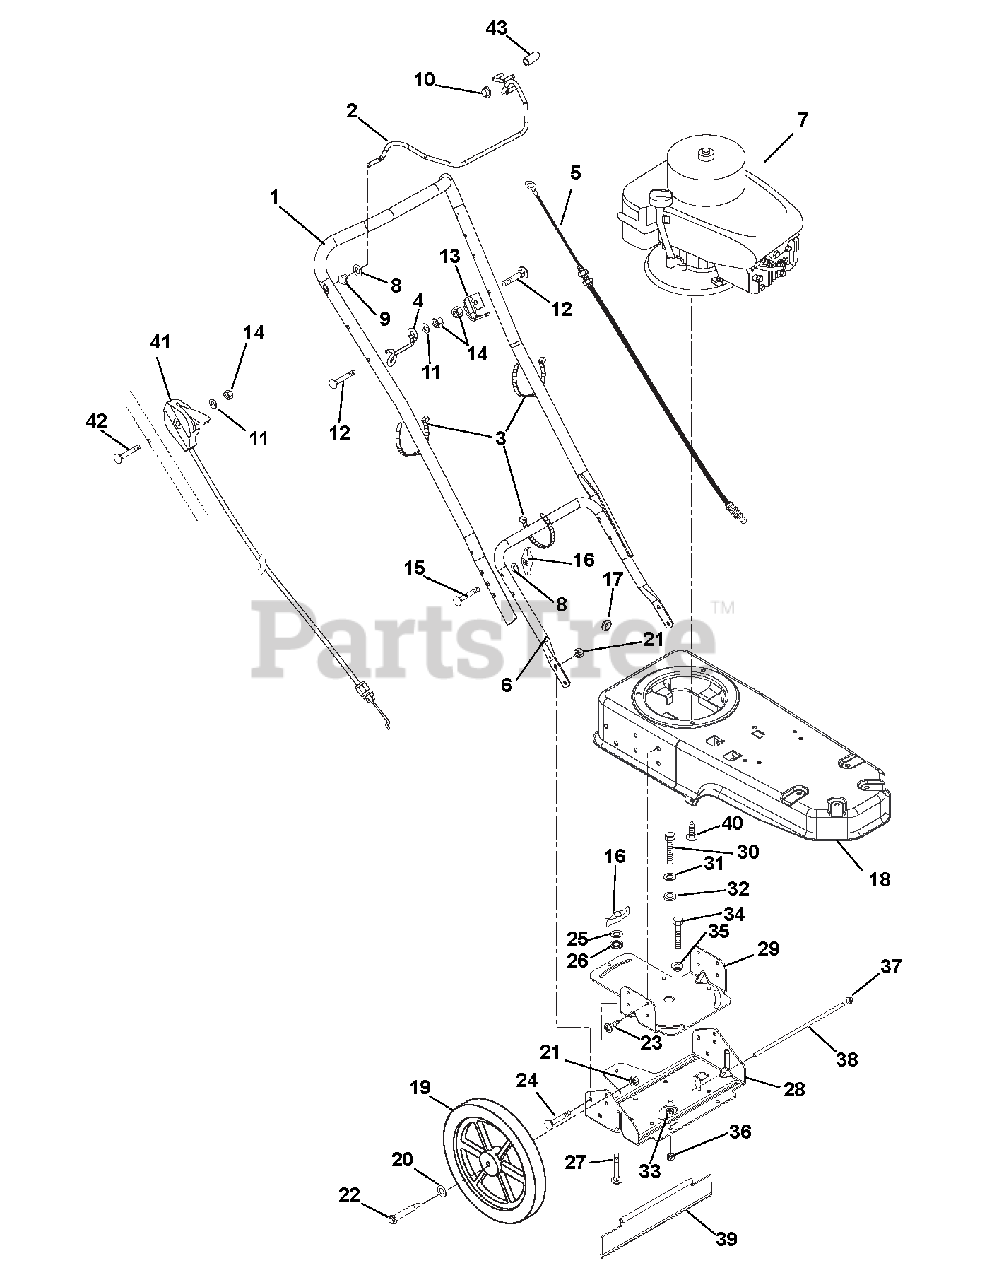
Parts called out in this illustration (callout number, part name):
1	HANDLEBAR - UPPER
2	BAIL SS LF
3	CABLE TIE LG 5-1/2
4	GUIDE - PULLCORD
5	CABLE - CONTROL
6	HANDLEBAR - LOWER
7	ENGINE, B&S 6.25HP CE
8	@WSHR-FL-STL.344X.688X.065YWZC
9	BSHG-FLG .325X.444X.440X.560
10	PUSH NUT, .25
11	@WSHR-FL-STL.281X.62X.065 YWZC
12	BLT-RDHDXLSQNK.25-20X1.25 G5ZC
13	ANCHOR - CABLE
14	@NUT-LK-CTR .25-20 YWZC
15	BLT-RDHDSQNKFT .31-18X2.0 G5YZ
16	KNOB,WING .31-18 UNC NYL/TALC
17	GROMMET .50 ID
18	FRAME - TRIMMER
19	WHEEL 14 X 1.75 X .50
20	WSHR-FL-STL .52X.827X.062 YWZC
21	@NUT-LK-CTR .38-16 YWZC
22	BLT-SHLDR .38-16X2.50 HWH G5
23	@SCR-TAP .38-16X.75 HWH TR YWZ
24	@BLT-RDHDSQNK .38-16X.75 G5YZ
25	@WSHR-FL-STL.38X.875X.083 YWZC
26	NUT-PUSH .312
27	@BLT-RDHDSQNK .31-18X1.00 G5YZ
28	BRACKET - AXLE - SWIVEL
29	BASE - SWIVEL
30	@BLT-HEX .50-13X1.00 GR5 YWZC
31	@WSHR-FL-STL.563X1.38X.109YWZC
32	SPACER .531 X 1.00 X .225
33	@NUT-LK-CTR .50-13 YWZC
34	@BLT-HEX .31-18X1.00 GR5 YWZC
35	BSHG-FLG .32X.500X.344X.880
36	@NUT-LK-CTR .31-18 YWZC
37	NUT-PUSH .312 DIA. PAL
39	GUARD - REAR - SWIVEL
40	@SCR-TAP .38-16X1.00 HWH TR YZ
41	CABLE, BRIGGS TRIMMER THROTTLE
42	BLT-RDHDXLSQNK .25-20X2.0 G5YZ
43	CAP, VINYL, .25 ID
